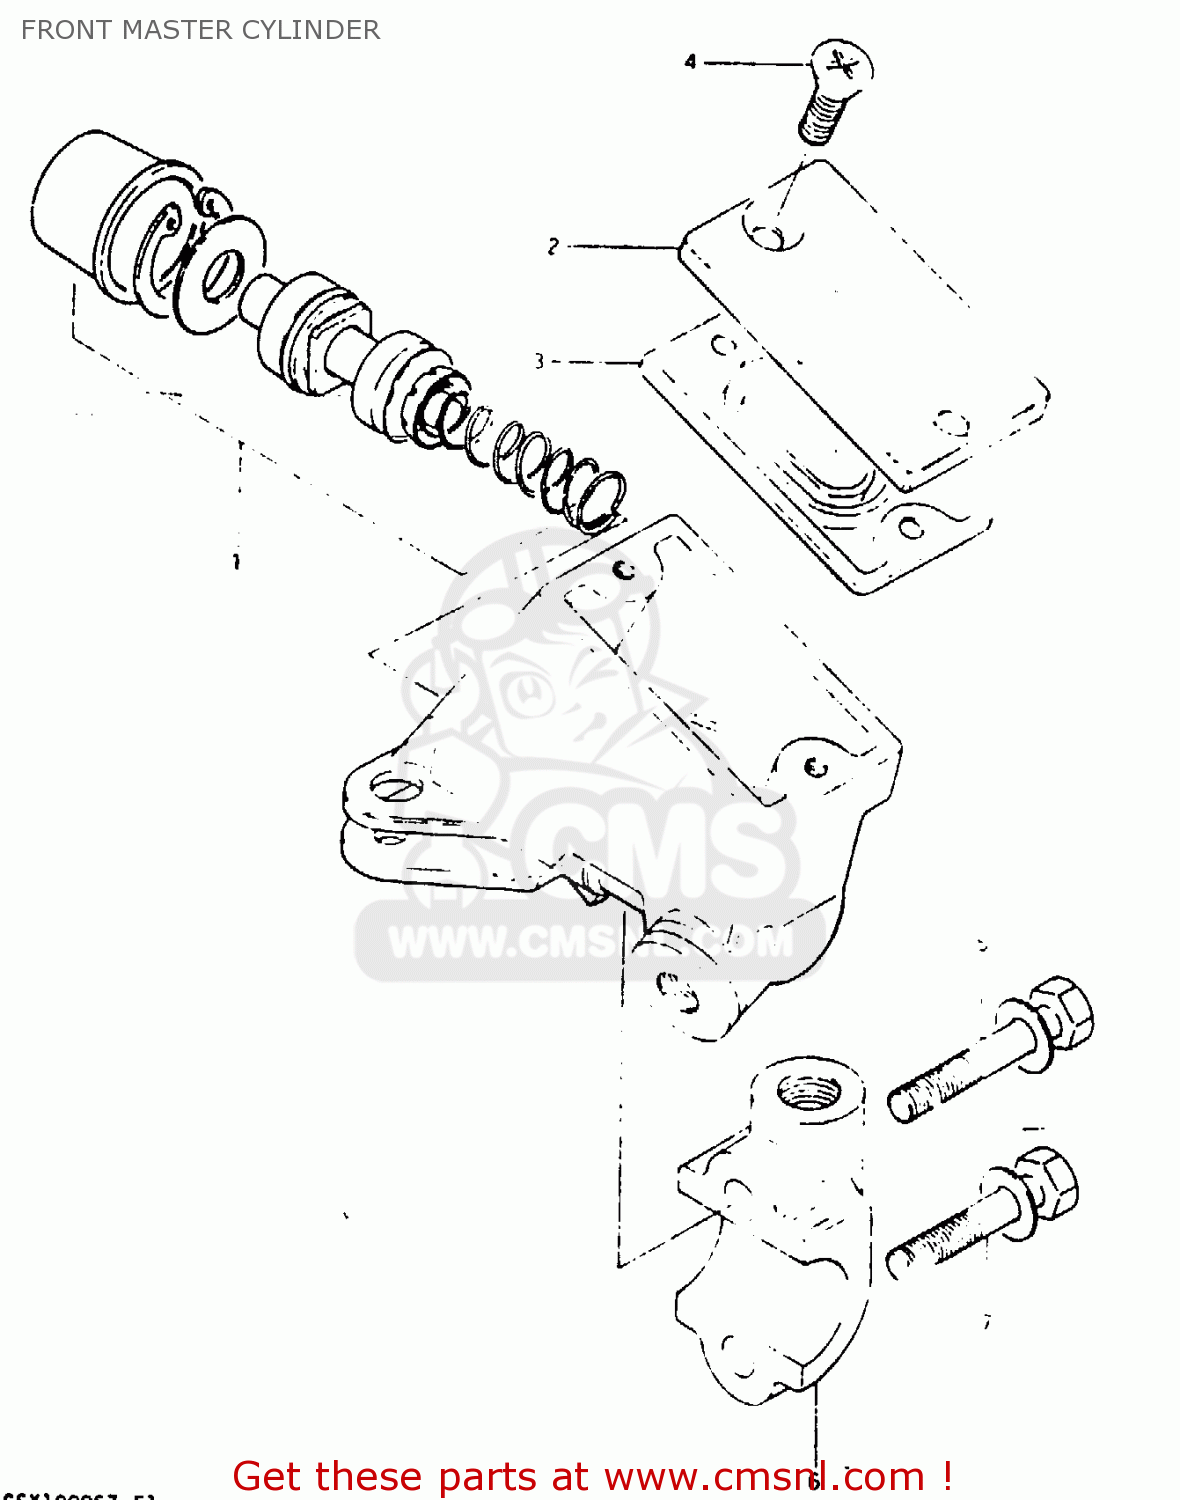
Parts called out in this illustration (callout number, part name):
1	PISTON & CUP SET
2	CAP
3	DIAPHRAGM,MASTER CYLINDER
4	SCREW,RESERVOIR CAP
5	BOLT,MASTER CYLINDER H
6	HOLDER
7	BOLT,MASTER CYLINDER H
